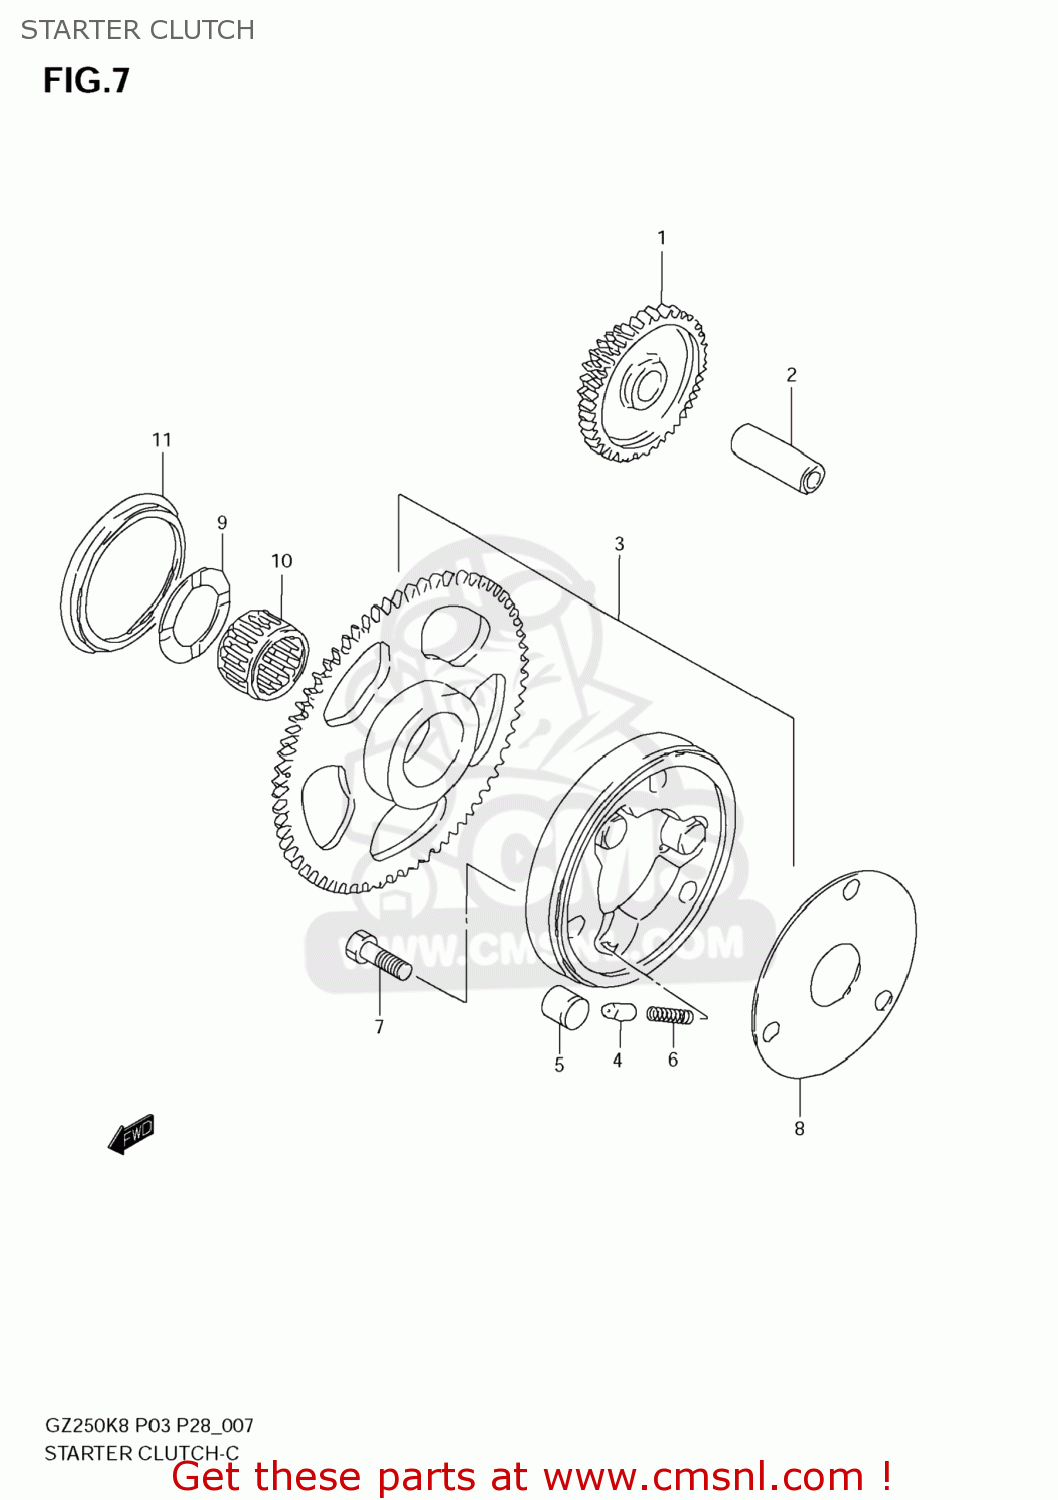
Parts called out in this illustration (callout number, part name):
1	GEAR,STARTER IDLE
2	PIN(7.4X13X40)
3	CLUTCH SET,STA
4	PIECE,PUSH
5	PIN(14X13)
6	SPRING
7	BOLT(8X20)
8	SHIM,STARTER CLUTCH HUB
9	WASHER(27X40X2.5)
10	BEARING(27X32X21.8)
11	SEAL,OIL(52X62X6.8)
